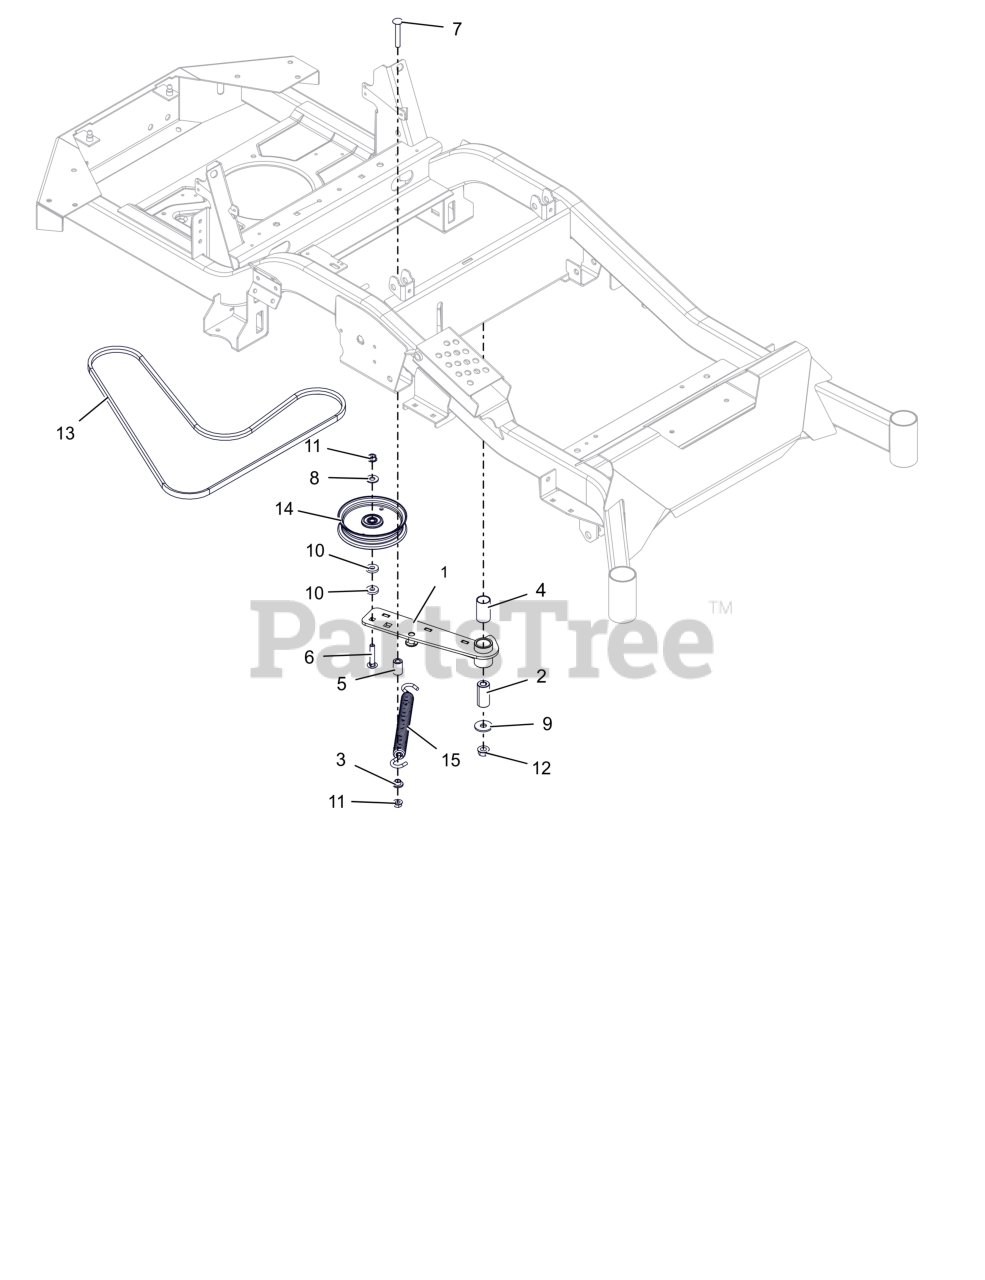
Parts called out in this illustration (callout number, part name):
1	WLDMT, HYDRO DRIVE IDLER ARM (BLACK)
2	BSHG, SPCR .502X.997X2.03 PM
3	BSHG-FLG .385X.500X.875X.406
4	BSHG, 1.00X1.125X1.937
5	BUSHING, SLV .380X.750X1.190
6	BLT, RHSN .38-16X2.00 G5 ZCC
7	BLT, RHSSN.38-16X2.50 G5 ZCC
8	WSHR,FLT .438X1.00X.083 ZCC
9	WSHR-FL-STL.511X1.44X.125ZC120
10	WSHR, FLT .406X1.00X.188 ZCC
11	NUT-LK-TOP-FLG .38-16 ZC120
12	NUT-LK-TOP-FLG .500-13 GF ZCC
13	V-BELT, 4L-WRAPPED
14	IDLER- FLAT - 5.00" X .75"
15	SPRING, EXTENSION
